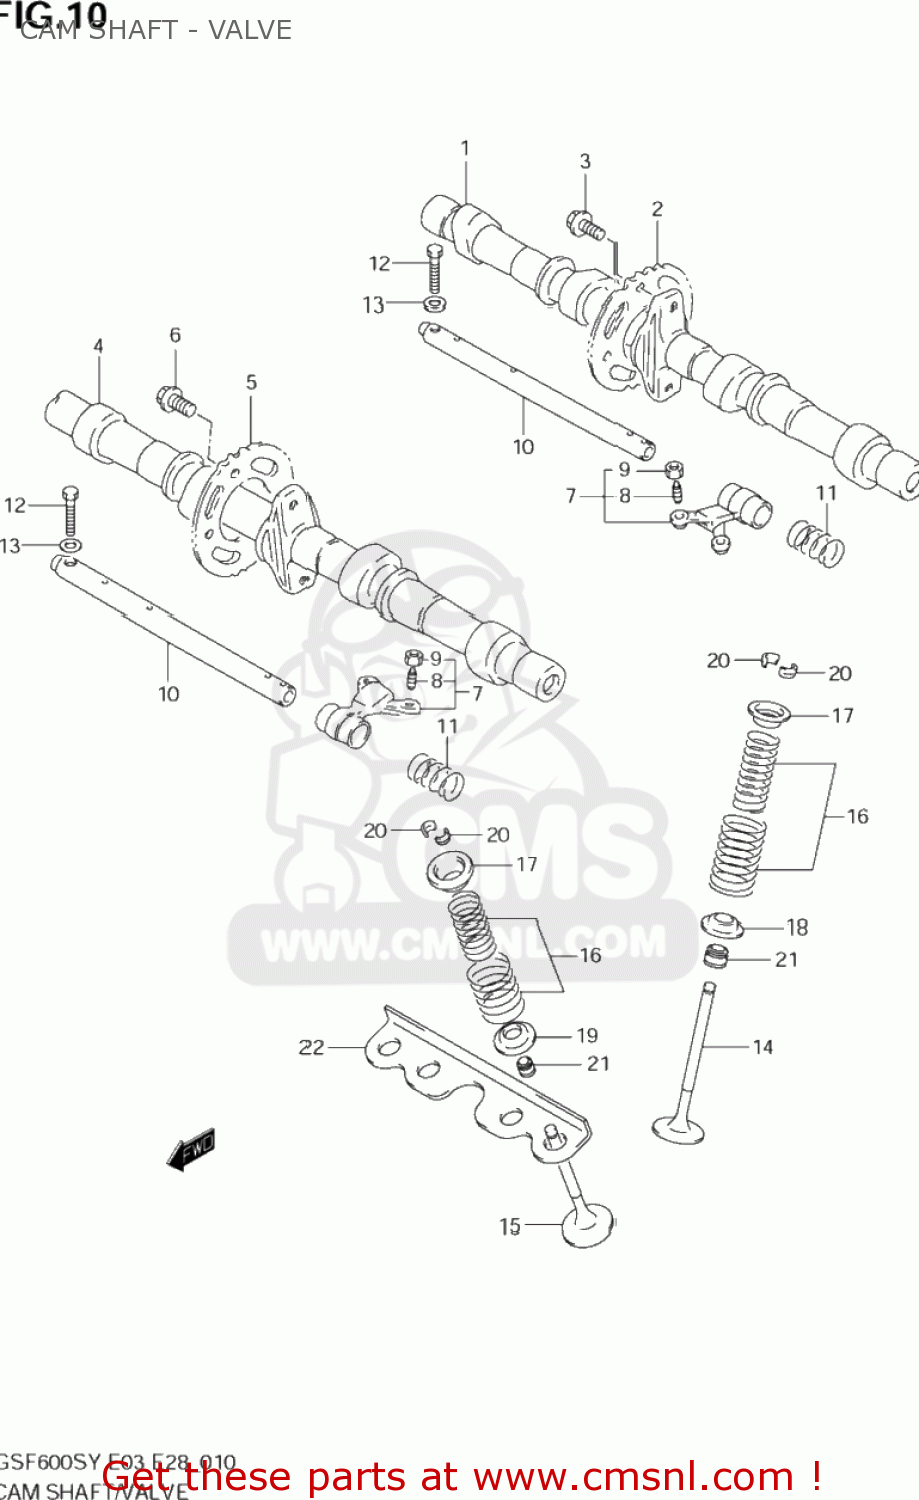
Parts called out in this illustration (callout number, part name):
1	CAMSHAFT,INTAKE
2	SPROCKET,CAMSHAFT
3	BOLT(7X11)
4	CAMSHAFT,EXHAUST
5	SPROCKET,CAMSHAFT
6	BOLT(7X11)
7	ARM,VALVE ROCKER
8	SCREW,TAPPET ADJUSTING
9	NUT,TAPPET ADJUSTING
10	SHAFT,VALVE ROCKER ARM
11	SPRING
12	BOLT(6X30)
13	WASHER
14	VALVE,INTAKE
15	VALVE,EXHAUST
16	SPRING SET,VALVE
17	RETAINER,VALVE SPRING
18	SEAT,VALVE SPRING
19	SEAT,VALVE SPRING EXH INNER
20	COTTER VALVE
21	SEAL,OIL(5X10X9.7)
22	PLATE,VALVE SEAT
